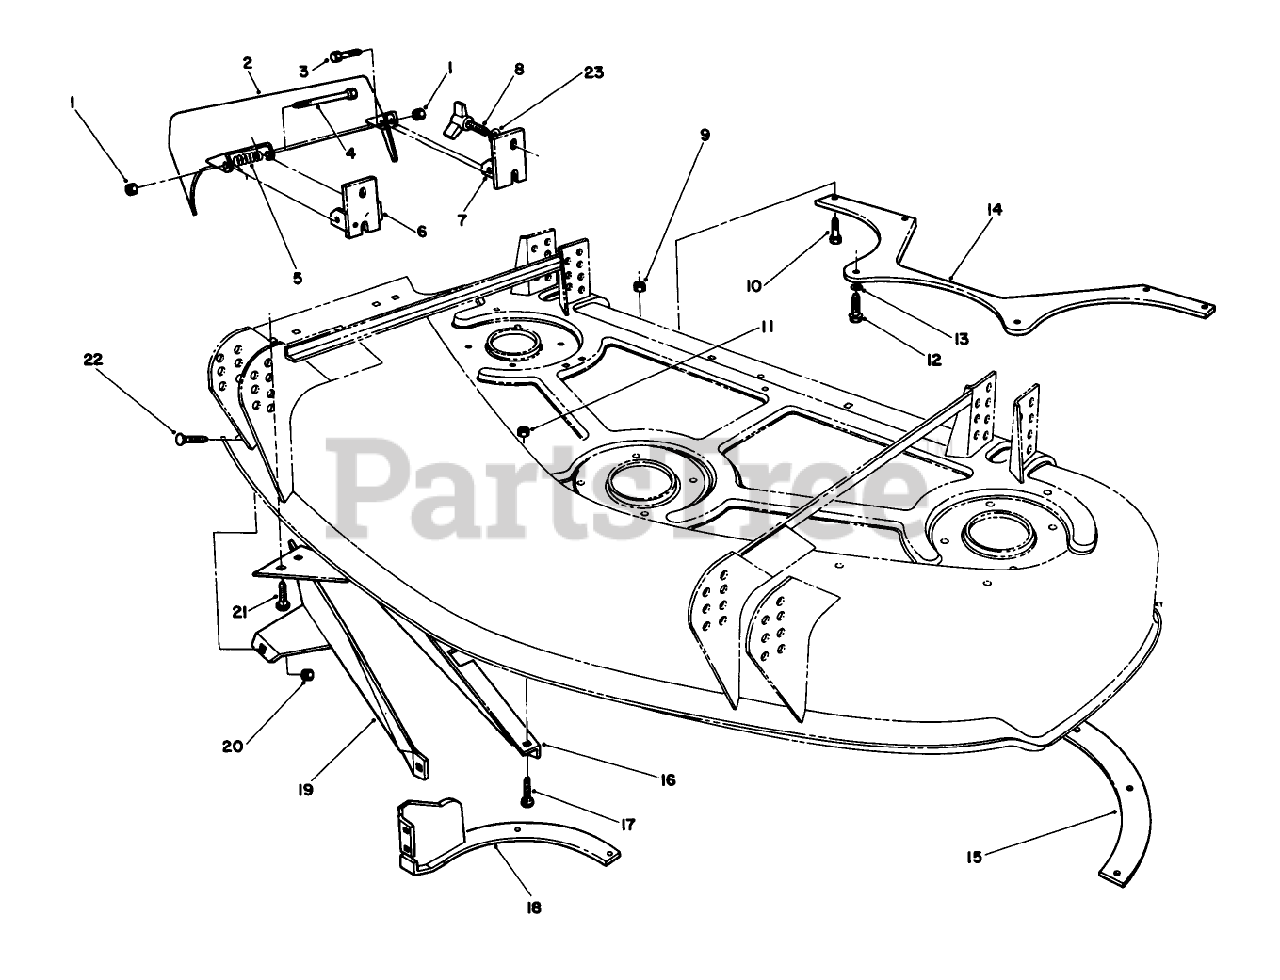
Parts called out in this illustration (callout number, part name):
1	NUT-HEX
3	SCREW-HH
4	SCREW-HH
5	SPRING
9	NUT-LOCK, NI
10	SCREW-HH
11	NUT-KEPS
12	SCREW-HHFTF
13	WASHER-FLAT
17	SCREW-CARR
20	NUT-KEPS
21	BOLT-CARR
23	WASHER-FLAT
